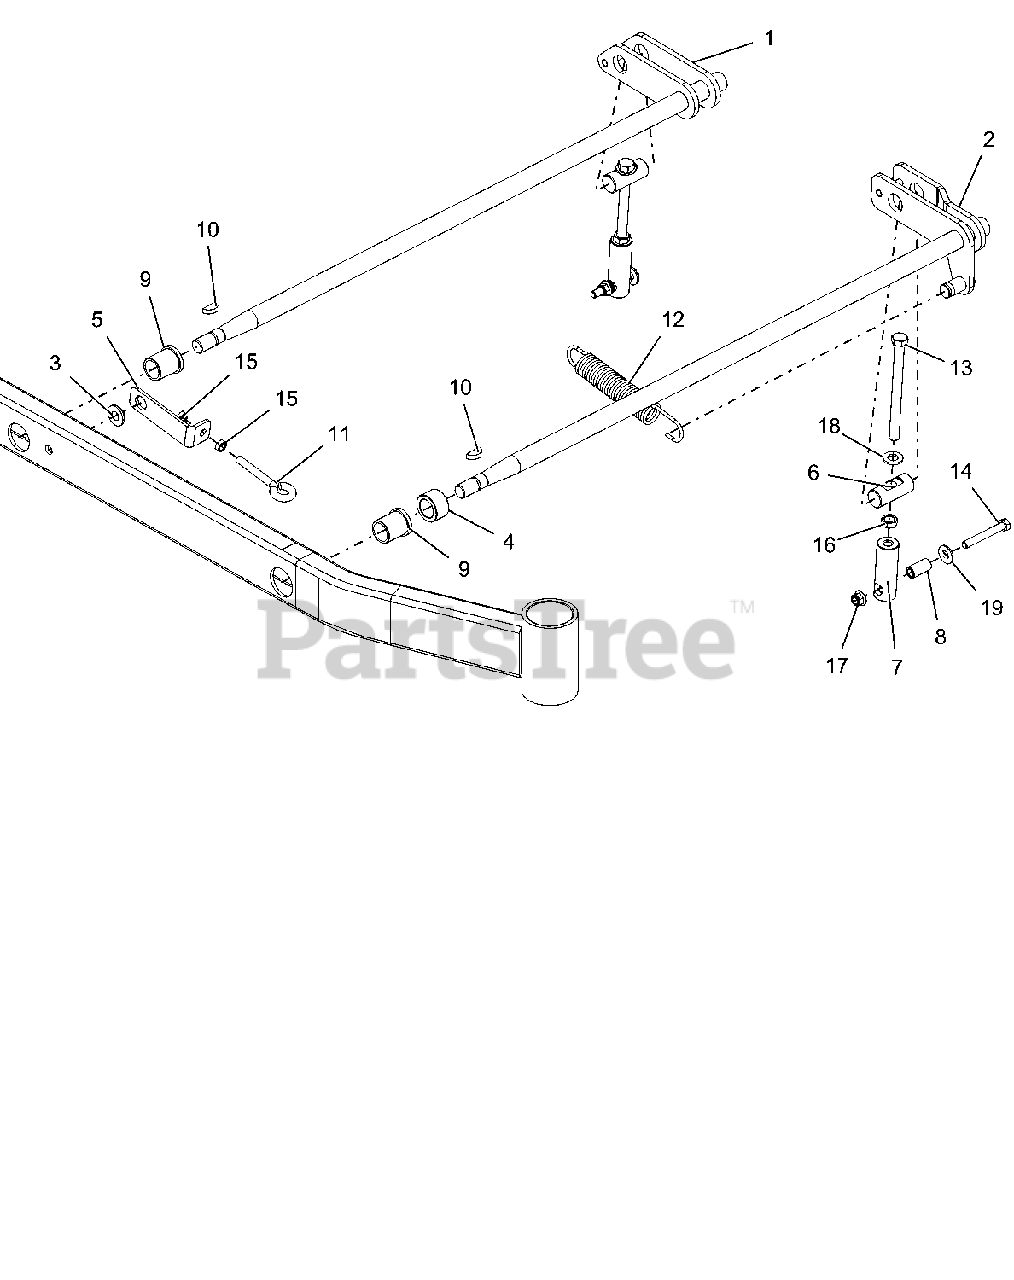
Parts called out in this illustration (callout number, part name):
1	REAR LH DECK LIFT ARM WMT- LF
2	FRT LH DECK LIFT ARM WMT- LF
3	BSHG-FLG .515X.750X.395X1.120
4	SPACER, 1.500 X 1.000 X .880
5	SPRING ANCHOR BRACKET - RED
6	PIN, DECK LIFT
7	LINK, DECK LIFT
8	SPACER, DECK LEVELING
9	BSHG-FLG 1.00X1.25X1.50X1.50
10	KEY-WDRF .25X1.00 HRD #15
11	BLT-EYE .375-16X2.50 YWZC
12	SG-TENS .162X1.25X8.25 WLD 25
13	BOLT,.50-13X6.00-2.50 LG THD
14	BLT-HEX .38-16X2.75 GR8 YWZC
15	NUT-HEX-JAM .375-16 YWZC
16	NUT-JAM .50-13 YWZC
17	@NUT-LK-NYL-FLG .38-16 YWZC
18	FLATWASHER 1/2 SAE HARD 15906
19	@WSHR-FL-STL.438X1.00X.083 YWZ
